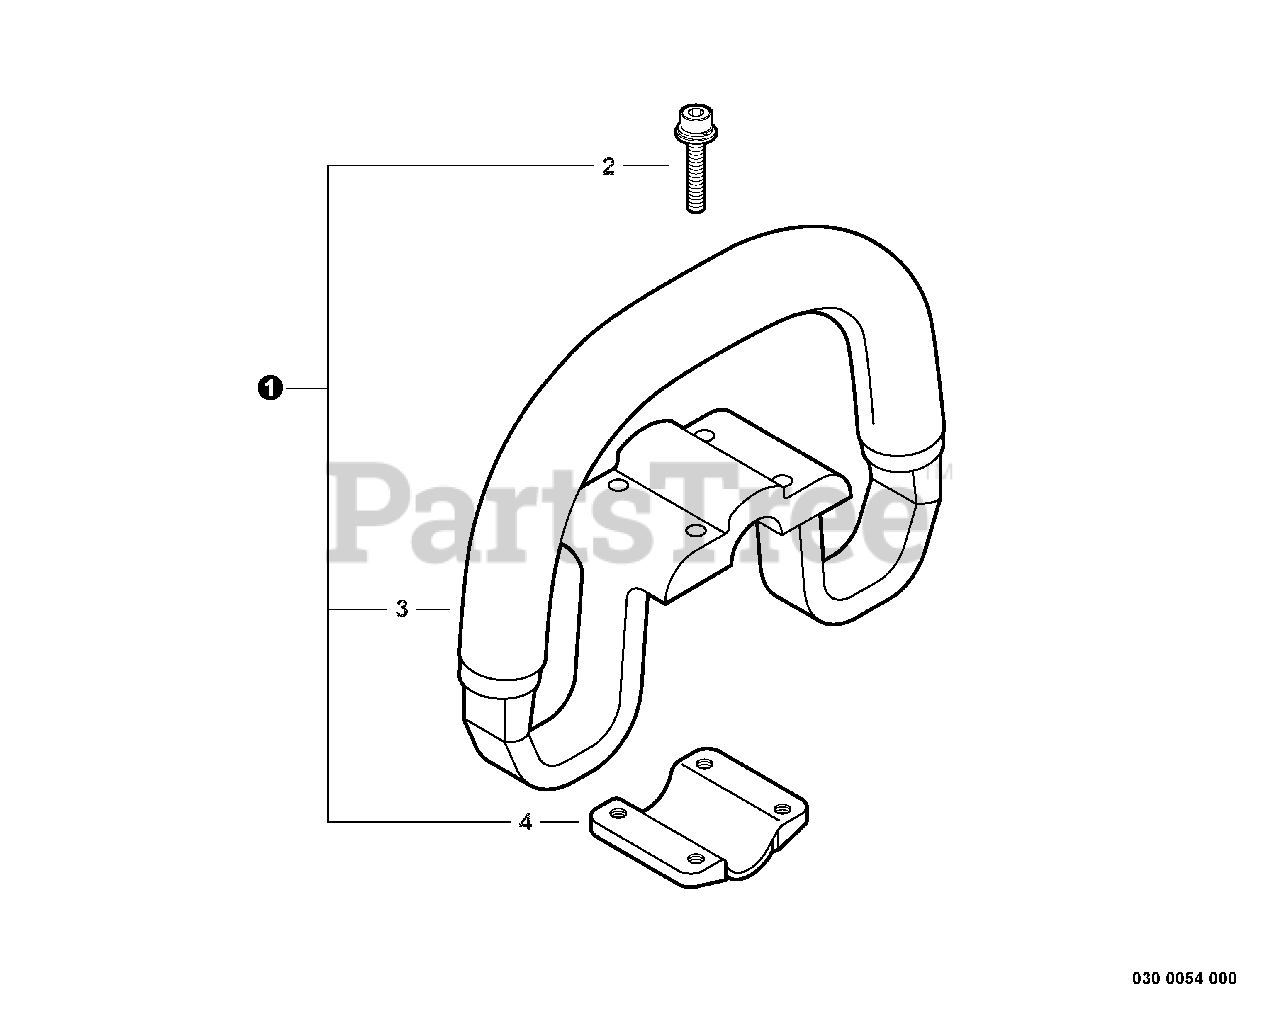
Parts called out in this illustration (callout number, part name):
1	HANDLE KIT
2	SCREW - 5X25
4	BRACKET, HANDLE - LOWER
